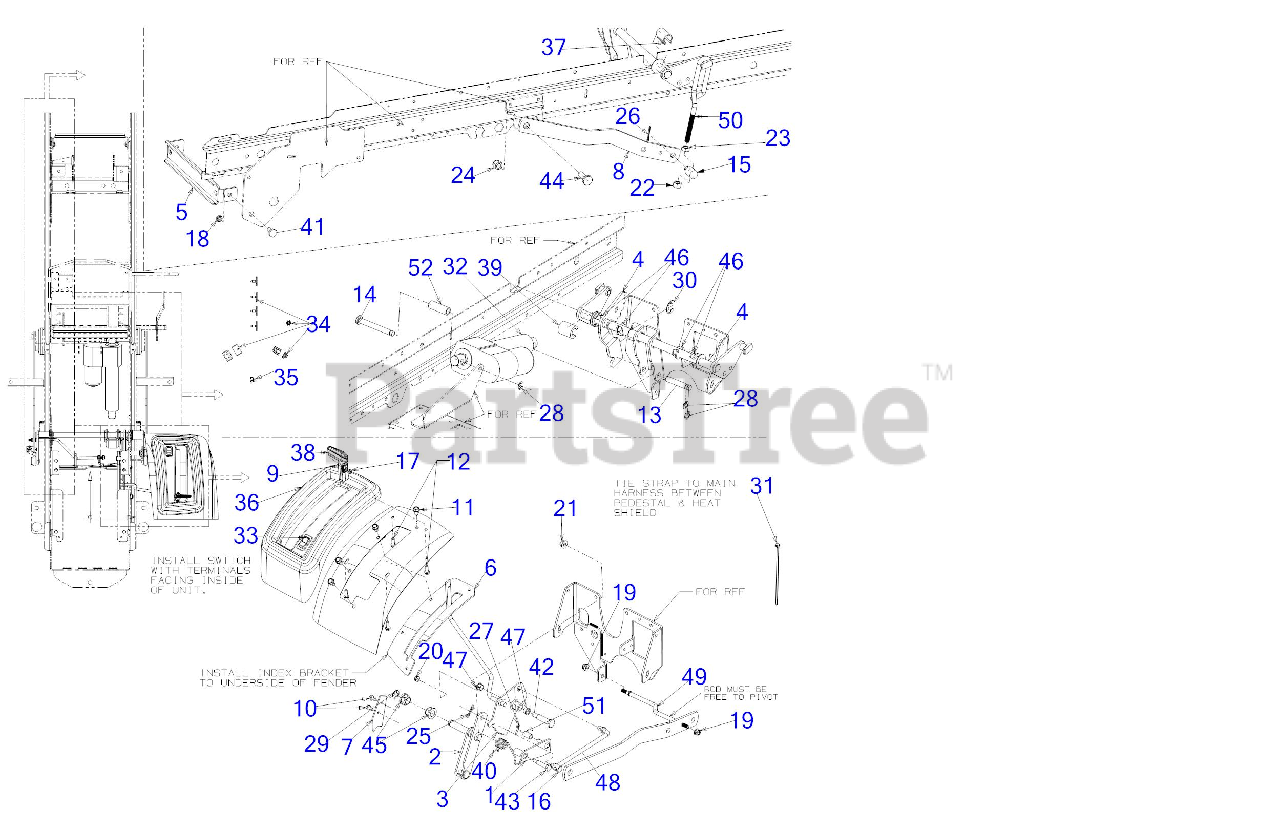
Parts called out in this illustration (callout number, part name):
2	HEIGHT SETTING ARM
3	HEIGHT POSITION LEVER
4	ELECTRIC LIFT SHAFT ASSEMBLY
5	FRONT HANGER BRACKET
7	HEX BEARING STOP PLATE
9	SCREW #10-24 x .62
10	SCREW 1/4-20 X.500
11	SCREW 5/16-18 x .625
12	SCREW 1/4-15 x .750
13	PIN .495 x 2.75
14	LIFT ACTUATOR PIN
15	LIFT LINK FERRULE
16	FERRULE 3/8-24 x .375
18	JAM LOCK NUT
19	FLANGE LOCK NUT 5/16-18
20	FLANGE LOCK NUT
22	HEX NUT NYLOK 1/2-13
23	HEX NUT
24	HEX LOCK NUT NYLON
25	BOW TIE COTTER PIN 1/4-5/16
26	COTTER PIN
27	COTTER PIN
28	E-RING FOR .500
30	RETAINING RING
31	7" CABLE TIE
32	ACTUATOR LIFT
33	PLOW LIFT SWITCH
34	DECK LIFT HARNESS
35	FUSE-30 AMP
36	FENDER COVER-ELECTRIC LIFT (RH)
37	SNAP SPACER .75
38	CUTTING HEIGHT KNOB
39	SPACER .76 x 1.465
40	TORSION SPRING
41	SHOULDER SCREW .500 DIA x .295
42	SHOULDER BOLT .498 x 1.635:3/8-16
43	SHOULDER SCREW .374 DIA. x 1.375 LG
44	SHOULDER BOLT
45	FLANGE BEARING
46	HEX FLANGE SPLIT BEARING
47	NYLINER BEARING
48	ADJUSTMENT LIFT ROD
49	DECK ANTI SWAY ROD
50	LIFT ADJUSTMENT LINK
51	SPACER .35X.50X.891 LG
52	SPACER .551X.750X2.06LG
